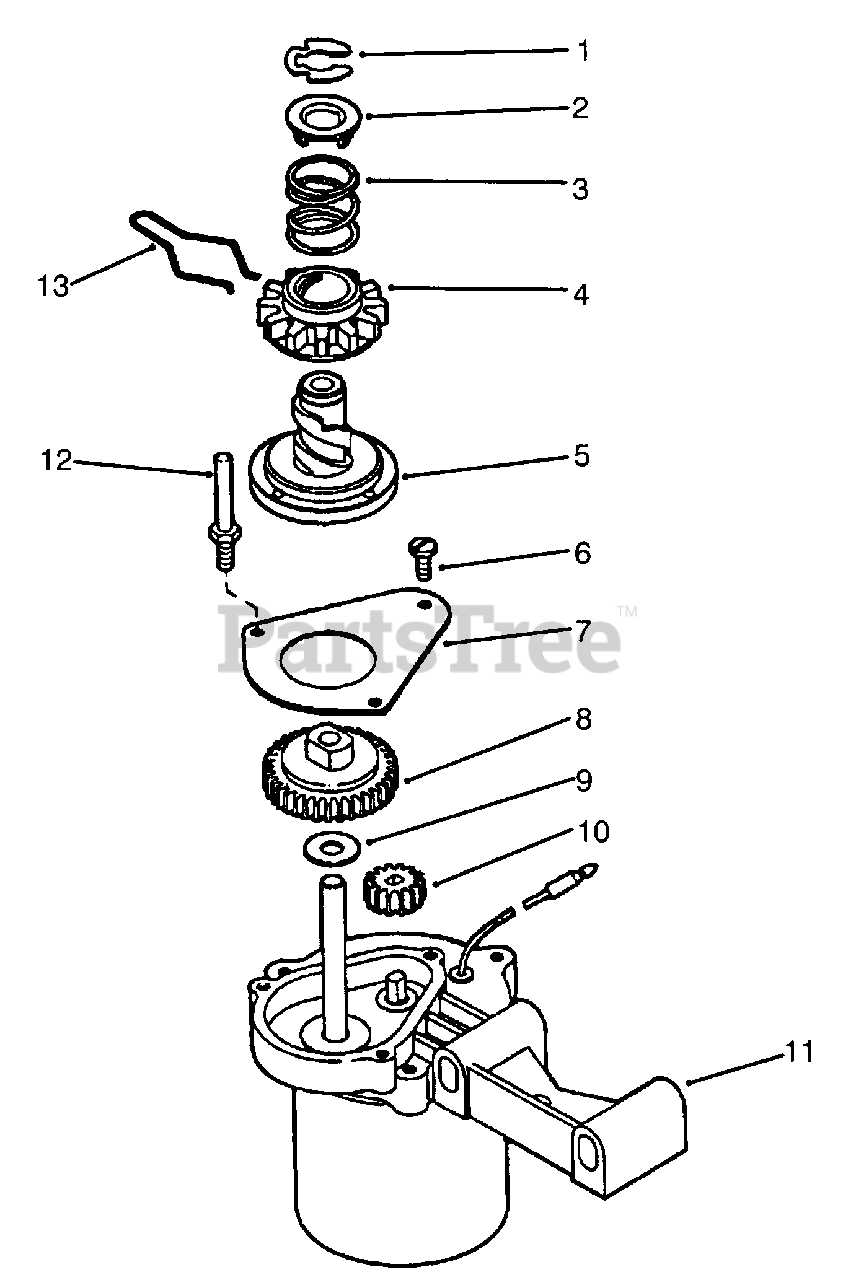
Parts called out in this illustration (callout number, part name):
1	Ring-Retaining
2	Washer-Stop
3	Spring-Pinion
5	Assy.-Clutch (Incl. Ref. #1-4 & 13)
7	Plate-Cover, Gear
8	Gear-Driven
9	Washer-Thrust
11	Assy.-Housing & Pin
12	Stud-Spring, Drag
13	Spring-Drag
